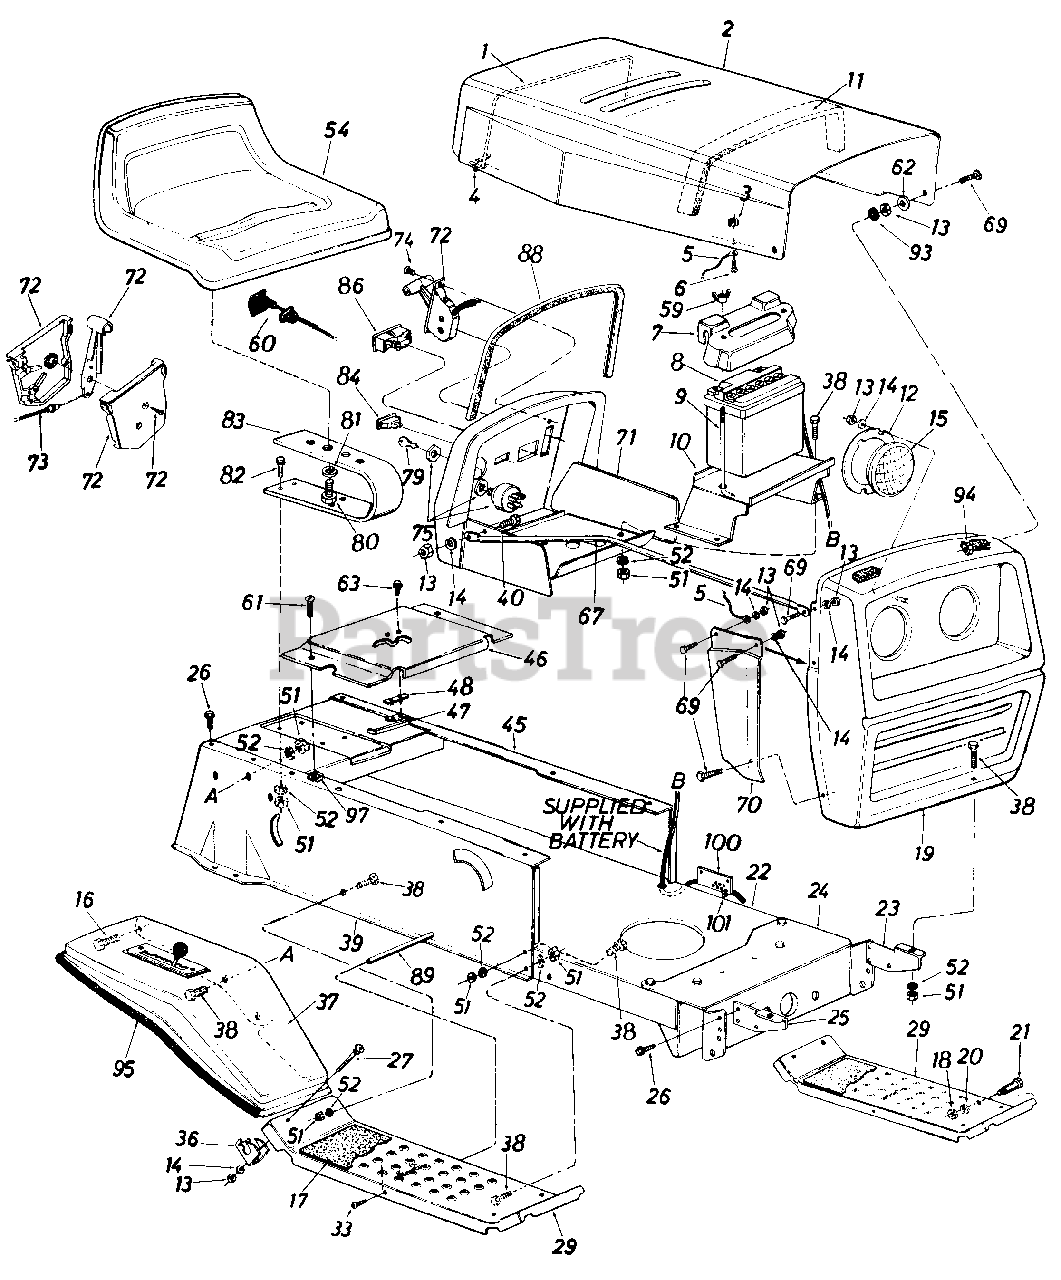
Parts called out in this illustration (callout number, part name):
1	Hood Spring
2	Hood
3	Hex Sems Nut #10-24 Thd.
4	Push Mount Tie
5	Hood Stop 7" Lg.
6	Truss Hd. Scr. #10-24 x '/2"
7	Battery Cover
8	12 Volt Battery
9	Battery Hold Down Rod
10	Battery Bracket
11	PVC Foam-Strip
12	Headlight Retainer
13	Hex Nut 1/4-20 Thd.
14	L-Wash. 1/4" I.D.
15	Headlight
16	Hex Wash. Hd. Tap Scr. 1/4 x 3/8" Lg.
17	Foot Pad
18	Hex Nut 3/8-16 Thd.
21	Shld. Bolt .50" Dia. x .84
22	Lower Frame
23	Grille Mount Brkt.-L.H.
24	Front Pivot Brkt.
25	Grille Mount Brkt.-R.H.
26	Hex Wash. Hd. AB-Tap Scr. 5/16 x .75" Lg.
27	Carr. Bolt 1/4-20 x 2.00" Lg.
29	Running Board
33	Truss Mach. Scr. 5/16-18 x .75" Lg.
36	Fender Clamp
37	Fender
39	R.H. Side Frame
40	Hex Bolt 1/4-20 x .62" Lg.
45	L.H. Side Frame
46	Shift Cover
47	Reverse Safety Switch
48	Insulator Nut Plate
51	Hex Nut 5/16-18 Thd.
52	L-Wash. 5/16" I.D.
54	Seat Ass'y.
59	Wing Nut 1/4-20 Thd.-Plastic
60	Choke Control 44.0" Lg.
61	Truss Mach. Tap Scr. #10 x .50" Lg.
62	Fl-Wash. .281 I.D. x .73 O.D.
63	Hex Wash. Hd. AB-Tap Scr. #8 x .50
69	Truss Hd. Scr. 1/4-20 x .75" Lg.*
70	R.H.-Grille Side Panel
71	Dash Panel Ass'y.
72	Throttle Control Box Ass'y.
73	Throttle Control Wire-35"
74	Truss Mach. AB-Tap Scr. #10 x .5" Lg.
75	Ignition Switch
79	Ignition Key
80	Hex Bolt 1/2-13 x 1.00" Lg. (Grade 5)
81	L-Wash. 1/2" I.D.
82	Hex Bolt 5/16-18 x 1.00" Lg.*
83	Seat Spring 5.5" High
84	Light Switch
86	Ammeter
88	Molding Strip 27" Lg.
89	Running Board Rod
93	Rubber Wash. 1/2" I.D. x 1.0 O.D. x .25"
94	Hex Sems Ins. L-Nut 1/4-20 Thd.
95	Trim Strip 31.0" Lg.
97	Speed Nut #10Z
100	Brake Cable Bracket
101	Cable Tie
